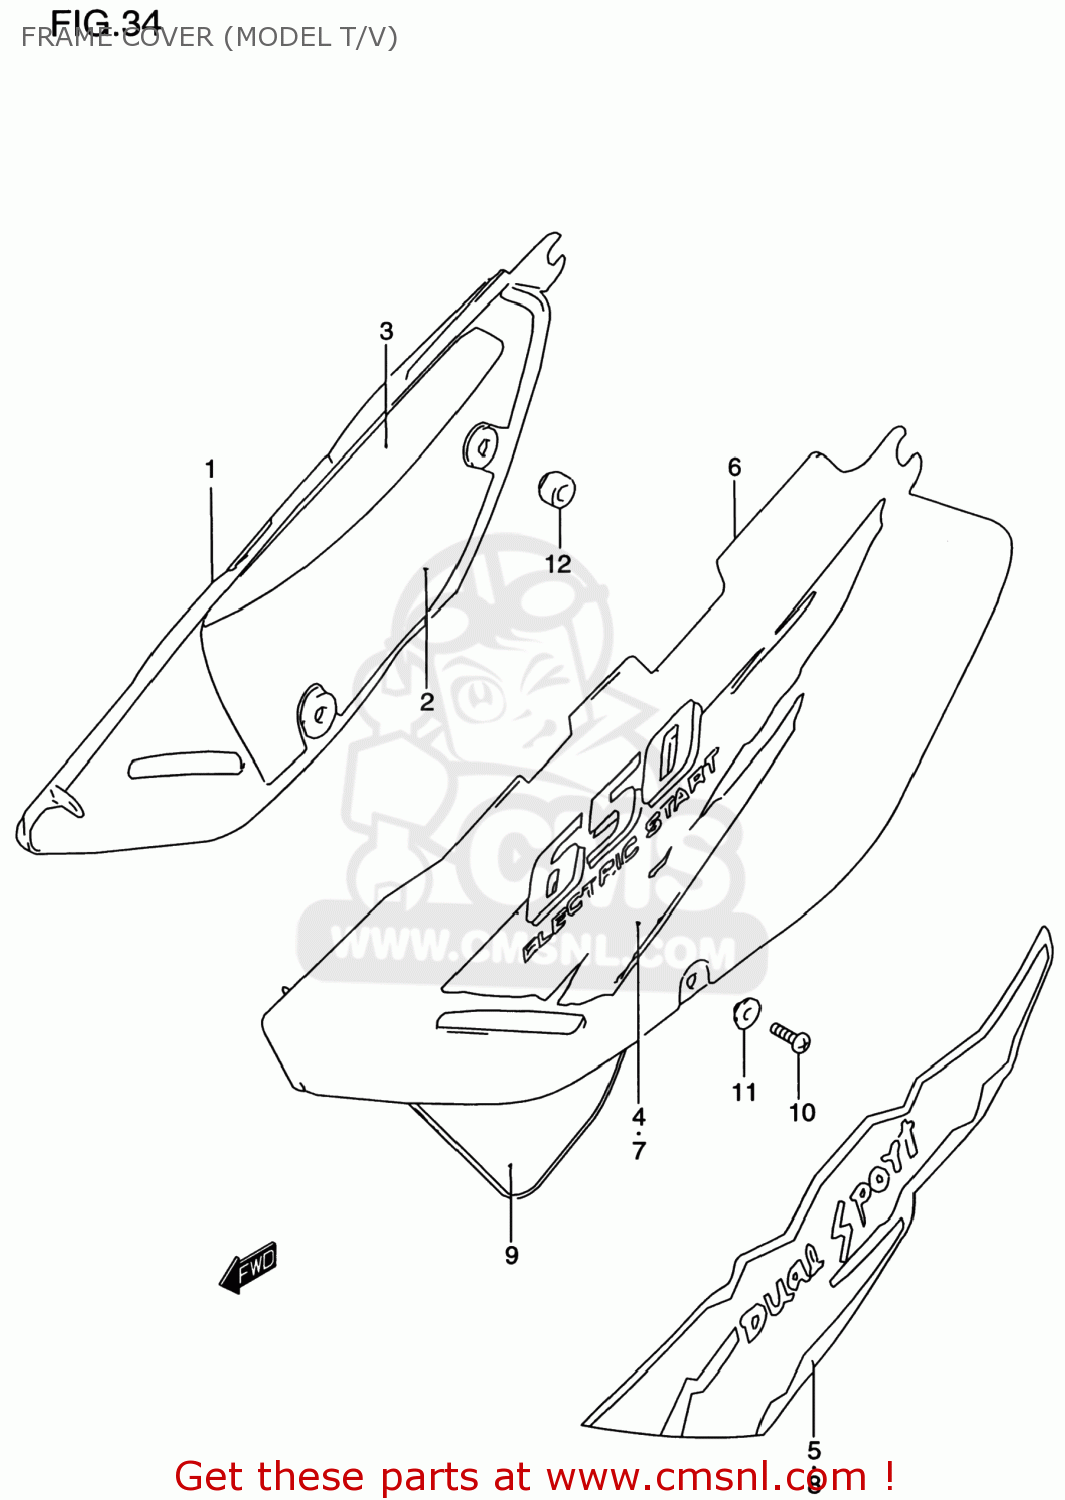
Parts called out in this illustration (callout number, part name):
1	COVER,FRAME,RIGHT
2	SHIELD,FRAME COVER,R NO.1
3	SHIELD,FRAME COVER,R NO.2
4	TAPE,FRAME COVER,R
5	TAPE,FRAME COVER,R
6	COVER,FRAME,LEFT
7	TAPE,FRAME COVER,L
8	TAPE,FRAME COVER,L
9	TAPE,LWR
10	SCREW
11	WASHER
12	CUSHION
